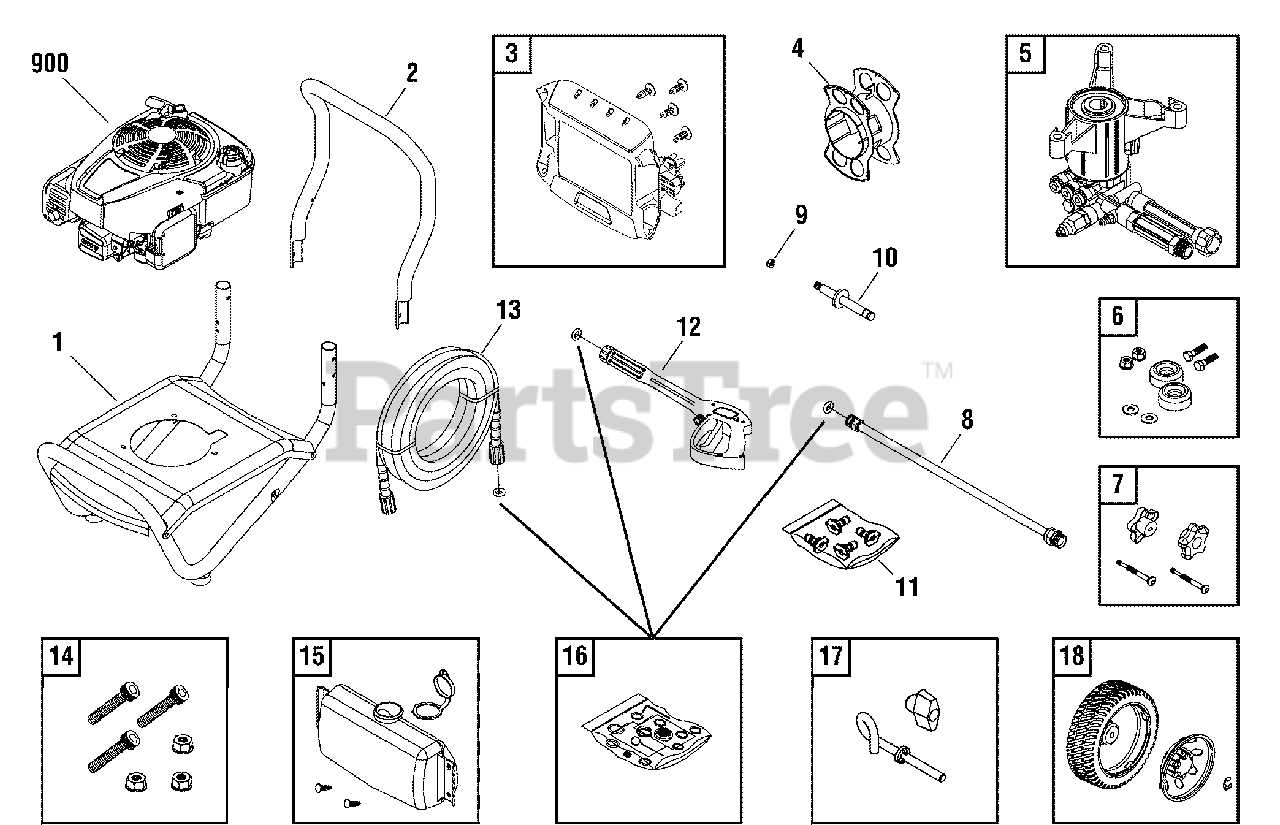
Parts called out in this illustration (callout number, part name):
6	MOUNT, Vibration
7	KIT, Hardware, Handle
8	EXTENSION, QC
9	NUT
11	KIT, QC Nozzles
12	GUN
13	HOSE
14	KIT, Hardware, Pump Mounting
16	KIT, O-Rings
18	KIT, Wheel
900	* ENGINE
